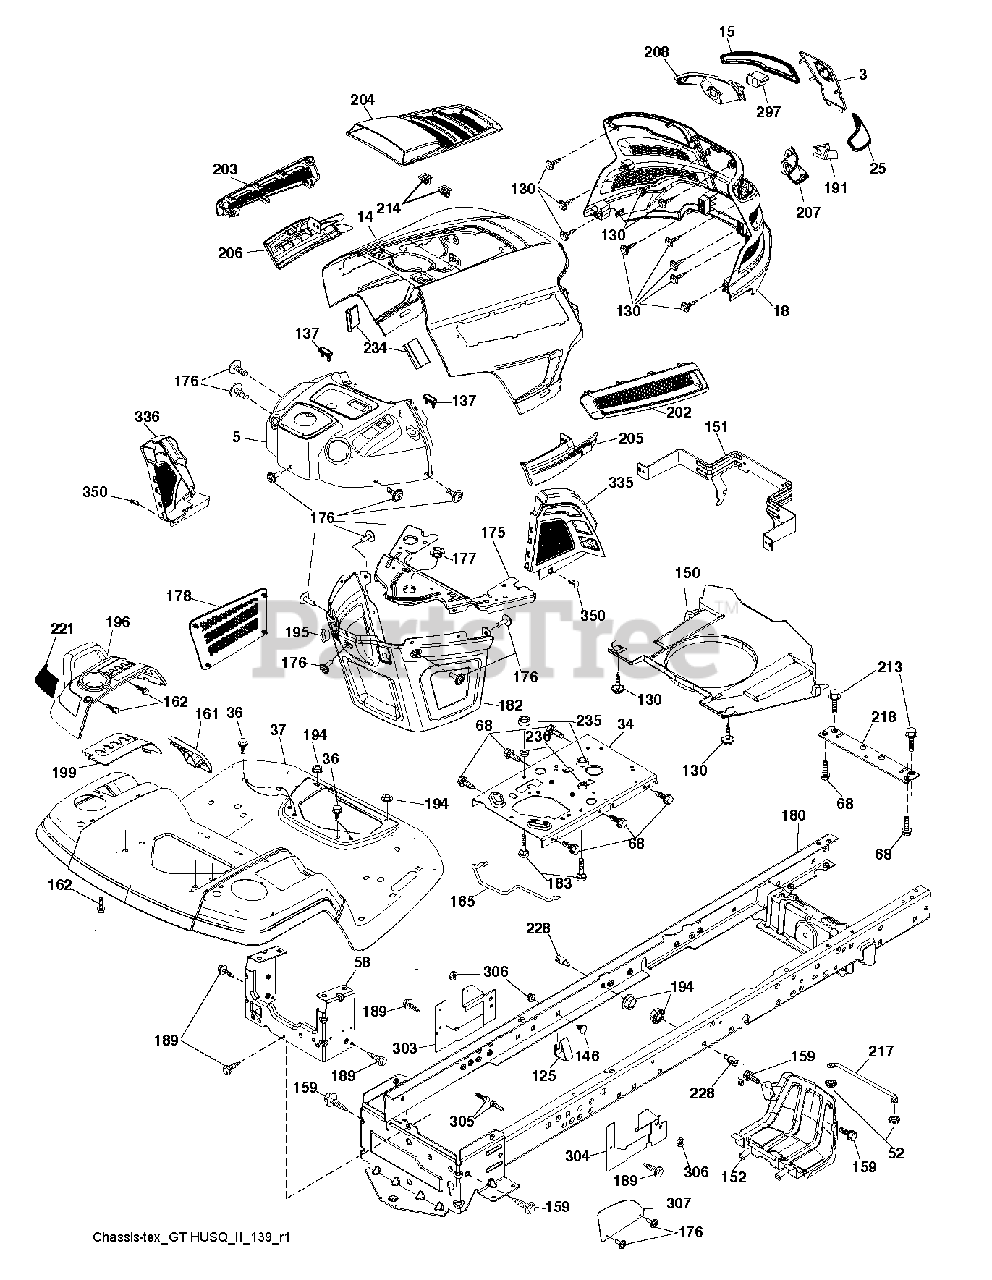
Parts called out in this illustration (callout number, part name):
3	APPLIQUE.SUBASM.GT.HUSQ.II
14	HOOD.ASM.HUSQVARNA.GT.TEX.ORAN
15	LENS.HEADLIGHT.LH.GTII.2011
18	GRILLE.SUBASM.GT.HUSQ.II
25	LENS.HEADLIGHT.RH.GTII.2011
34	PLATE.ENGINE.WELDED.CHASSIS
36	SCREW 5/16"
37	FENDER.PNT.TX.GT.CH/FW/DL.HUSQ
52	LOCKNUT
58	DRAWBAR.UPPER.2PC,LRG.FENDER
68	SCREW LT
125	CLIP.FUEL.LINE
130	SCREW.#10 X 0.750.BOS
137	BUMPER DASH
146	BOLT.RDHD.SHT.SQNK.3/8-16X5/8
150	AIR DUCT.GTV2(1.66"RING HEIGHT
151	BRACKET.PIVOT.HOOD.GT.HUSQ.II
152	SHIELD.BROWNING.PNT.GT.V2
159	SCREW, 3/8-16X3/4
161	CONSOLE.WINDOW.FUEL.HUSQ.GT
162	SCREW.HI-LO.CONSOLE
165	SUPPORT.TANK.REAR.W/TEX
175	PLATE.CROSSMEMBER.HUSQ
176	SCREW.#10-24X5/8.RN.QU
177	BUSHING, STEERING
178	CARGO.ASM.NET.TXGT.W/C
180	CHASS.WLDMNT.TLT.12GA/2PC.20"
182	DASH.LOWER.COMMON.12V.ADAPTOR
183	BOLT.5/16-18X1-1/4 FULL THD
189	SCREW
191	INSERT.REFLECTIVE.RH.HUSQ.GTII
194	NUT LOCK HEX FLANGE 5/16-18
195	PLUG.HOLE.DASH.LOWER.12V.BLK
196	SUBASM.CONSOLE.HUSQ.GT.DECKLFT
199	PLATE.DECK.LIFT.HUSQVARNA.GT
202	VENT.SIDE.RH.GT.HUSQ.II.
203	VENT.SIDE.LH.GT.HUSQ.II.498
204	VENT.TOP.HUSQ.GT2
205	SIDE.TRIM.RH.GT.HUSQ.II
206	SIDE.TRIM.LH.GT.HUSQ.II.GRAY
207	BEZEL LIGHT.RH.GT.II.MYLAR
208	BEZEL LIGHT.LH.GT.II.MYLAR
213	BOLT
214	CLIP.RETAINER.TINNER.
217	ROD.PIVOT.HOOD
218	X-PIECE.HOOD.STOP.NON/
221	REFLECTOR.LH.TEX GT HU
228	STUD.FASTNER.W/ANTI-ROTATE
234	BUMPER.HOOD.TEX.HUSQVARNA
235	SPACER FENDER
236	NUT.CENTERLOCK.5/16-
297	INSERT.REFLECTIVE.LH.HUSQ.GTII
303	SHIELD CHASSIS LEFT
304	SHIELD CHASSIS RIGHT
306	NUT LOCK FLG 3/8-16 UNC
307	SHIELD UPPER PEDAL
335	COVER.LOWER.DASH.RH.BLACK
336	COVER-LH.LOWER.DASH.GT2.BLACK
350	CLIP.X-MAS.TREE
